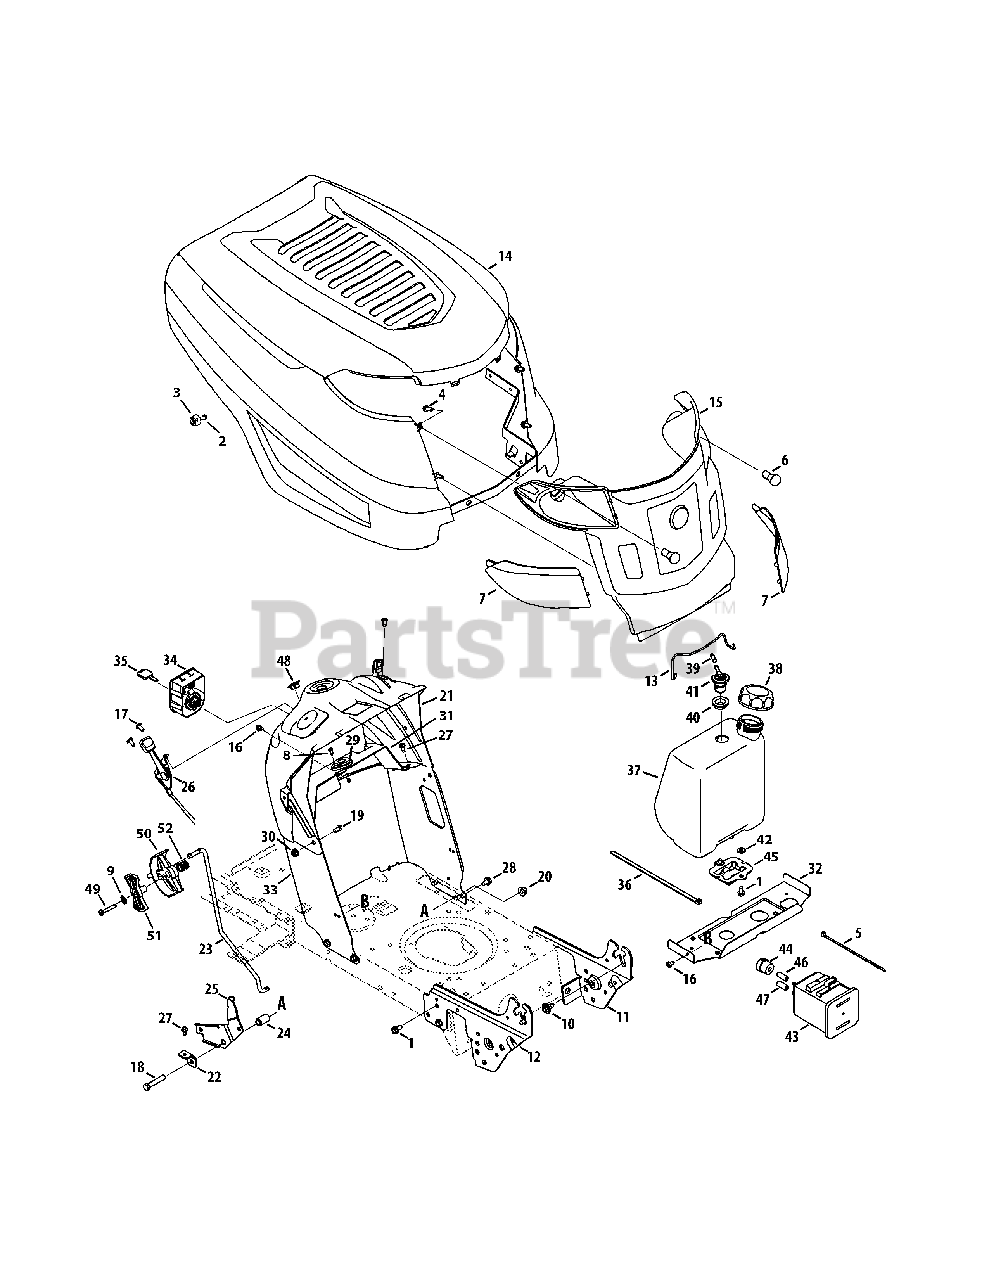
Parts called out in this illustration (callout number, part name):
1	Screw 5/16-18 x .750
2	Screw, #12-16 x 1.25
3	K-Style Bumper
4	Screw, 1/4 x .750
5	Cable Tie
6	Miniature lamp 12V socket
7	Grill Lens - LH
7	Grill Lens - RH
8	Screw, #10-16 x .500
9	Lock Washer, 1/4
10	Shoulder Screw .43 x .29
11	Suppport Bracket LH - Black
11	Suppport Bracket LH - Red
12	Suppport Bracket RH - Black
12	Suppport Bracket RH - Red
14	Hood
16	Screw, 1/4-20 x .500
17	Screw 1/4-20 x .500
18	Hex Screw 3/8-16 x 2.00
19	Hex Screw, 5/16-18 x .625
20	Flange Lock Nut 3/8-16
21	Dash, Upper
22	Speed Latch Tab
23	Speed Control Rod
24	Flange Spacer .39 x .671 x 1.095
25	Transmission Speed Latch
26	Throttle/Choke Control Cable
27	Hex Screw Washer 1/4-20 x .500
28	Screw 5/16-18 x .625
29	Bearing, .628 ID x 1.36
30	Flange lock Nut 5/16-18
31	Bracket, Steering Support - Black
31	Bracket, Steering Support - Red
32	Gas Tank Support Bracket - Black
32	Gas Tank Support Bracket - Red
33	Dash, Lower NWNDW - Black
33	Dash, Lower NWNDW - Red
34	Key Switch Module
36	Cable Tie
37	Fuel Tank, 1.5 Gallons
37	Fuel Tank, 1.36 Gallon, CARB
38	Fuel Cap
38	Fuel Cap, 1.5 Gallon
38	Fuel Cap, CARB
39	Hose Vent, 3/16
40	Rubber Grommet
41	Rollover Valve
42	Washer, Flat, .344 x .750 x .120
43	Canister, Carbon, 5 Gallon
44	Filter, Vent, Canister
45	Bracket., Adapter, Canister
46	Hose, Fuel, Low Perm., White
47	Hose, Fuel, Low Perm., Yellow
48	Choke Plug
49	Hex Washer Screw, 1/4-20 x 1.50
50	Shift Lever
51	Index Control
52	Compr. Springing, .72 OD x .78
